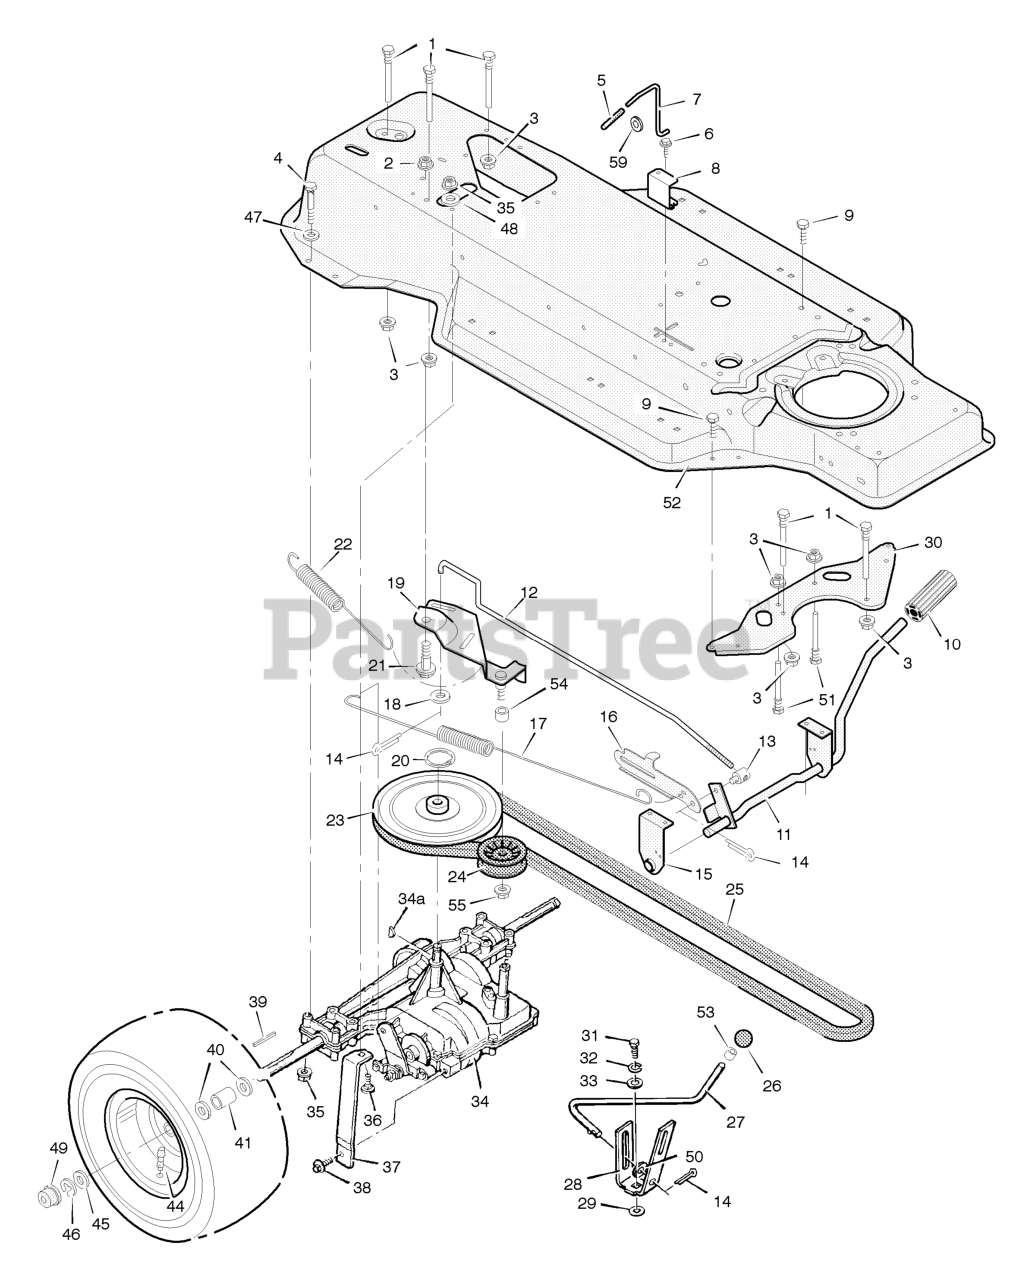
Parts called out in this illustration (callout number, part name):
1	Guide, Belt
2	Locknut, Flange
3	Nut, Flange
4	Bolt, Hex
7	Rod, Control -Park Brake
8	Guide, Bracket
10	Clutch and Brake Pedal
11	Lever Assembly
12	Rod, Clutch
13	Nut, Adjustable
14	Pin, Cotter
15	Bracket, Support
16	Latch, Park Brake
17	Spring, Brake Extension
18	Washer
19	Bracket Assembly, Idler
20	Ring, Retainer
21	Bolt, Shoulder
22	Spring, Drive Extension
23	Pulley, Motion Drive
24	Pulley, Backside Idler
25	Belt, Motion Drive
26	Knob, Shift Lever
27	Lever, Shift
28	Yoke, Shift
30	Plate, Belt Guide
31	Bolt, Hex
32	Lockwasher
34	Transaxle, Peerless **
34A	Woodruff Key No. 9
35	Nut, Flange
36	Bolt, Carriage
37	Support, Transaxle
39	Key, Square
41	Spacer, Transaxle
43	Wheel & Tire Assembly
44	Stem, Valve
47	Washer
49	Hub Cap
50	Washer
51	Guide, Belt
52	Frame Assembly
53	Ring, Tolerance
55	Nut
59	Grommet, Parking Brake
